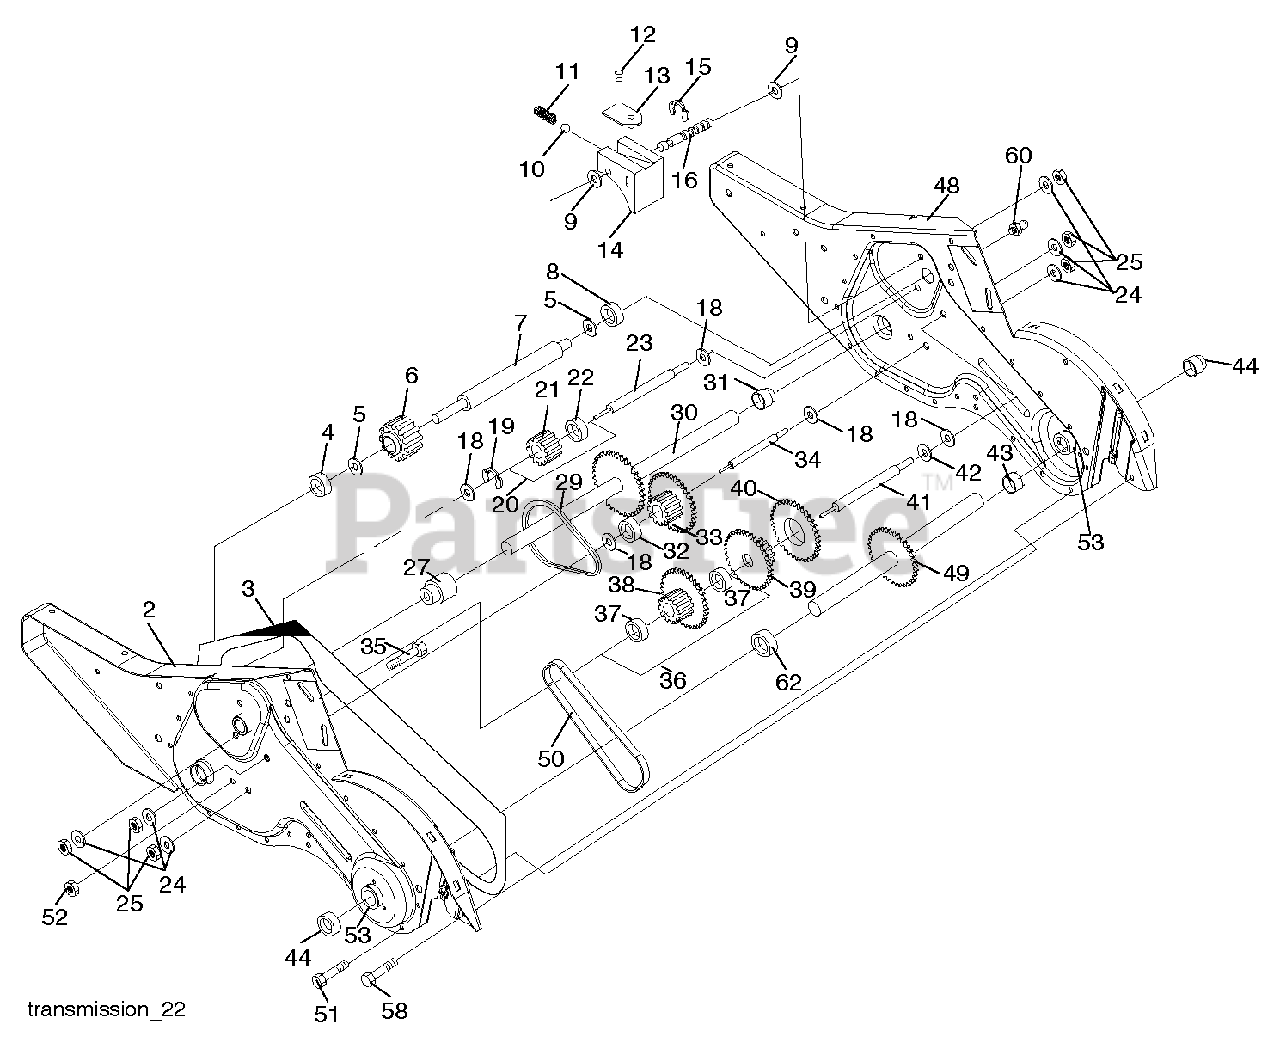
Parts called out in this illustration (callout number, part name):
1	TRANSMISSION.ASM.14/17.CRT.14
2	GEARCASE.ASM.CRT.LH.W/BEARING
3	GASKET.GEARCASE.CRT/DRT.TILLER
4	NEEDLE BRNG LT
5	THRUST WASHER
6	PINION INPUT CRT TILLER
7	SHAFT.INPUT."D".TILLER
8	BEARING TI
9	WASHER, SEAL (2 2)
10	STEEL BALL KIT
11	SPRING-SHIFT CRT
13	BRACKET ASM.SHIFT.CRT
14	SHIFT FORK TI
16	SHAFT.SHIFTER.TILLER
20	GEAR ASSY CRT
21	GEAR-REV IDLR CRT
22	NEEDLE BEARING TI
24	LOCKWASHER
25	NUT.ASF.HEX.7/16
27	BEARING.GROUND.DRIVE
30	GROUND SHAFT ASS'Y
31	BEARING, SHAFT RH CRT
33	SPRCKT 8 GEAR CRT
34	SHAFT.SECONDARY.REDUCTION.CRT
35	SCRW WHIZ LOK CRT
36	SPROCKET.ASM.W/BEARING.TILLER
37	BEARING
38	SPROCKET, TINE
41	SHAFT.REDUCTION.TILLER
42	BRNG RACE T
44	SEAL ASM, OIL
48	GEARCASE.ASM.CRT.RH.W/BEARING
49	SHAFT.ASM.TINE
50	CHAIN.TILLER
53	BEARING KIT
58	BOLT SHOULDER 1/4-20 UNC X.875
60	FITTING.GREASE.TAPERED
62	SPACER.1.015X1.50X.650
